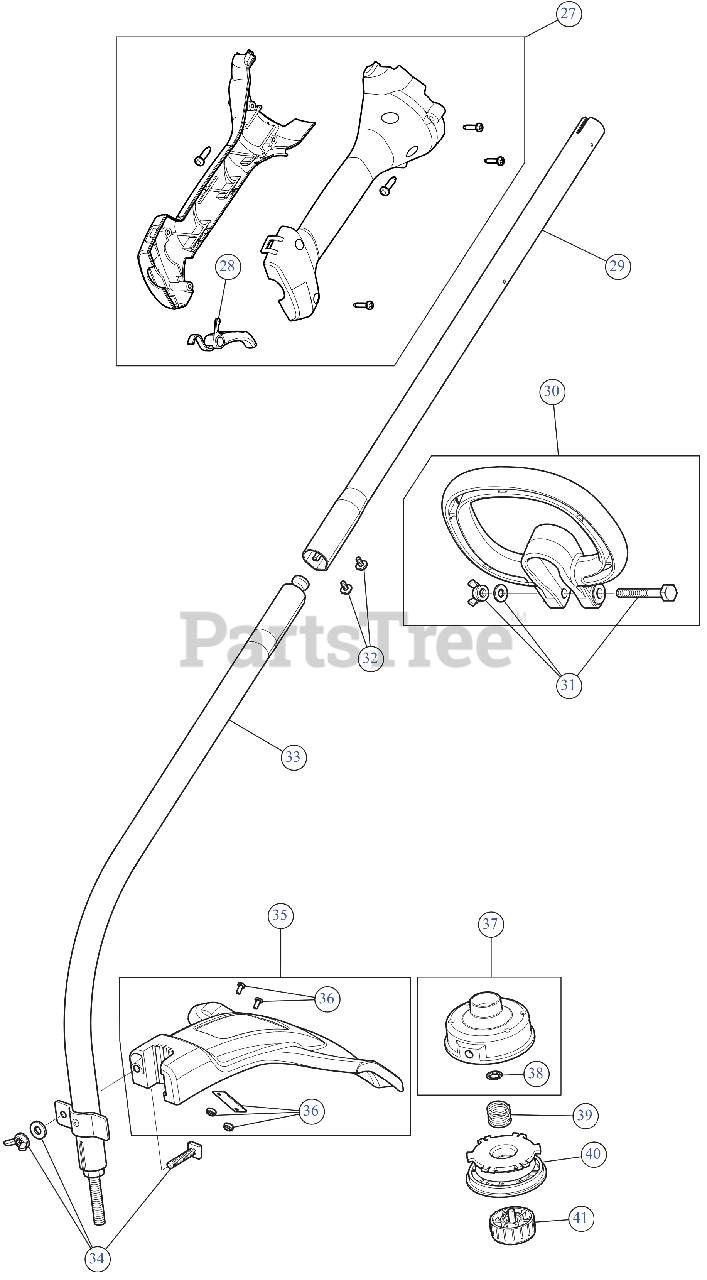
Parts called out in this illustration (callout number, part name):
27	THROTTLE GRIP ASSEMBLY
28	THROTTLE TRIGGER
29	UPPER BOOM ASSEMBLY
30	HANDLE
31	HANDLE HWD
32	SCREW 8-32X3/8
33	LOWER BOOM ASSEMBLY
34	BLADE GUARD MOUNTING HARDWARE
35	GUARD ASSEMBLY
36	BLADE ASSEMBLY CUTOFF
37	REEL:OTR W/RET
38	RETAINER .625 OD 2
39	SPRING-SPOOL
40	REEL-INNER SPOOL
41	BUMP HEAD KNOB ASSEMBLY
